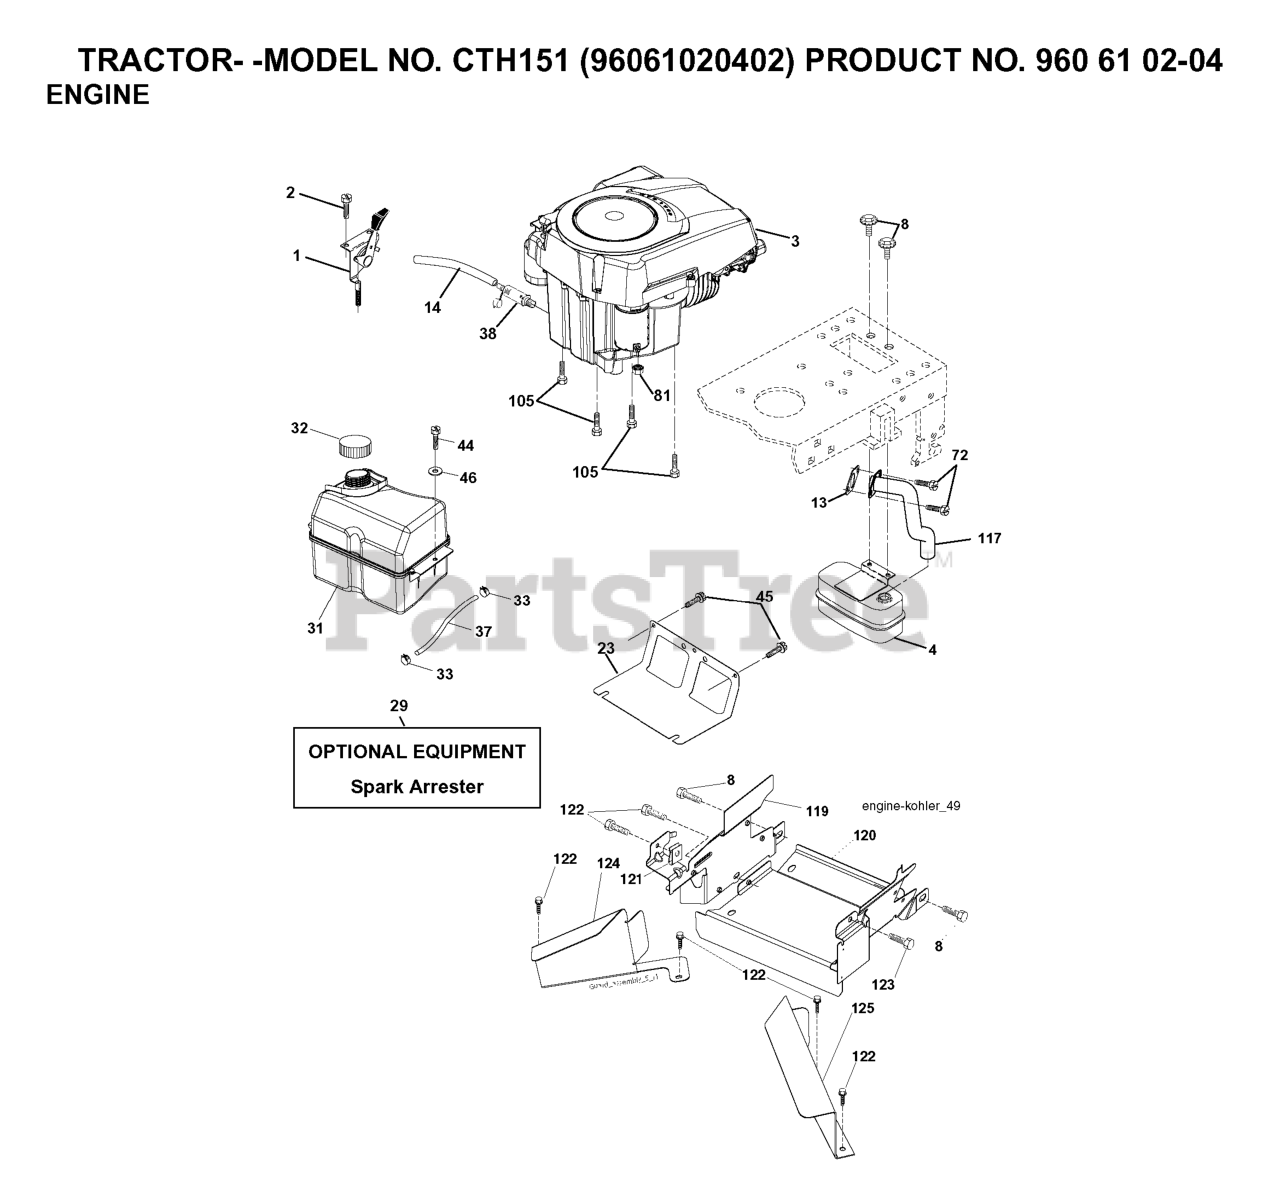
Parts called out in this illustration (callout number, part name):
1	CONTROL.TH/CK.C.
2	SCREW
4	MUFFLER.SINGLE.CYL.KOHL/B&S
8	BOLT.5/16-18UNCX3/4 W/SEMS.BLK
13	GASKET.EXHAUST.KOHLER
14	TUBE, DRAIN OIL ASM.
23	SHIELD.BROWNING.DBR.GUARD
29	KIT.SPARK ARRESTOR 794945 B&S
31	RP TANK FUEL FRT 1.5 GAL
32	FUEL CAP
33	HOSE CLAMP
37	LINE.FUEL.20
38	PLUG DRAIN OIL EASY
44	SCREW HEXWSHR 1/4-20X3/4
45	SCREW, 3/8-16X3/4
72	SCREW.SOCKET HD.5/16-1
81	NUT
105	SCREW 3/8-16X1
117	RP.TUBE.EXHAUST.KOHL.COURAGE
119	LENKRAD
120	GUARD 532199767
122	SCREW.1/4-20X5/8
123	SCREW, 5/16-18 X 1/2
126	SCREW
